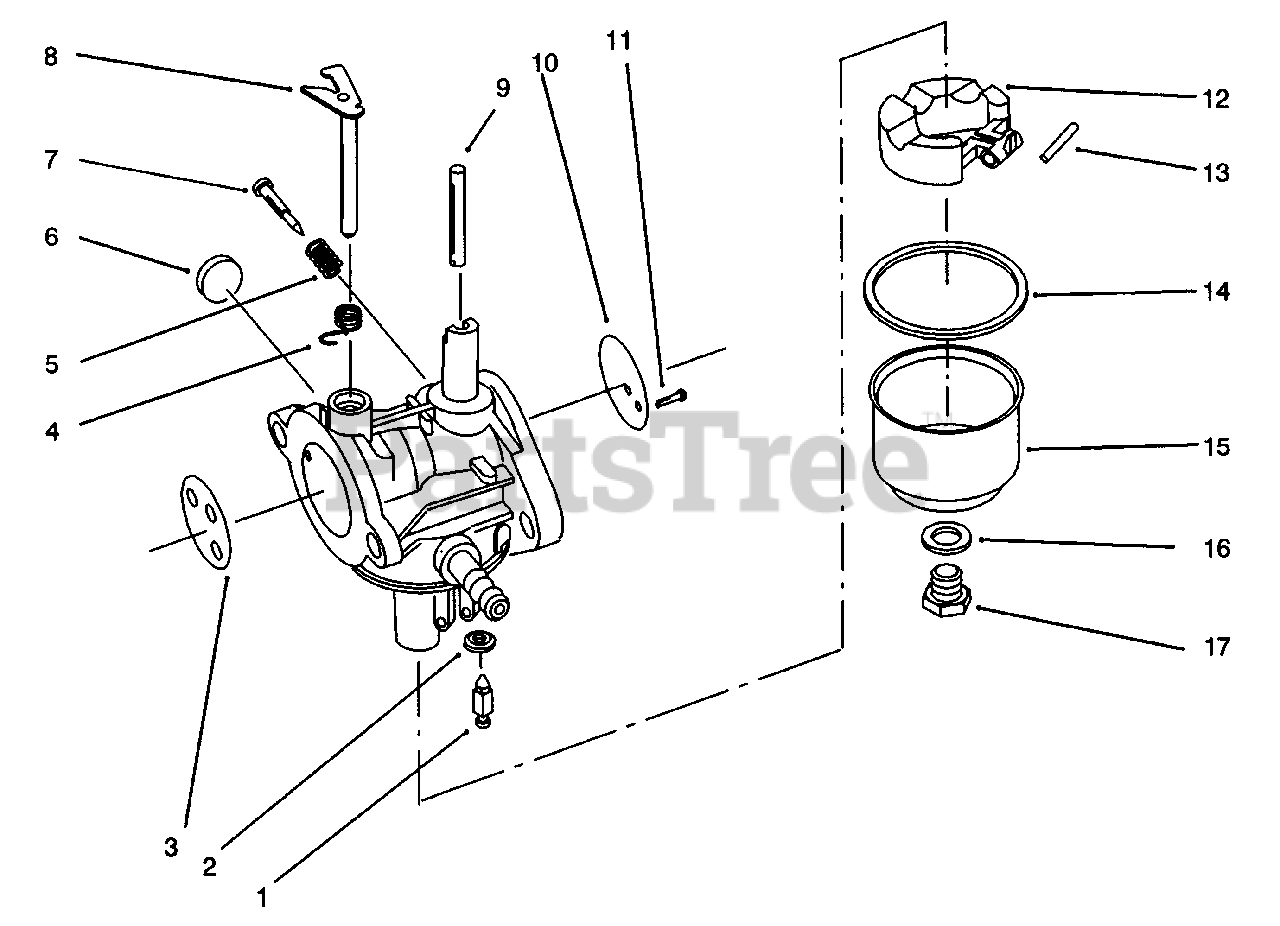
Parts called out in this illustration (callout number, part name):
1	Valve Inlet Needle
2	Seat-Valve
3	Valve-Choke
4	Spring-Choke Return
5	Spring-Idle Needle
6	Plug-Welsh
7	Needle-Idle
8	Shaft-Choke
9	Shaft-Throttle
10	Valve-Throttle
11	Screw-Throttle Valve
12	Float
13	Shaft-Float
14	Gasket-Bowl
15	Bowl-Fuel
16	Gasket-Bowl Retainer
17	Screw-Bowl
